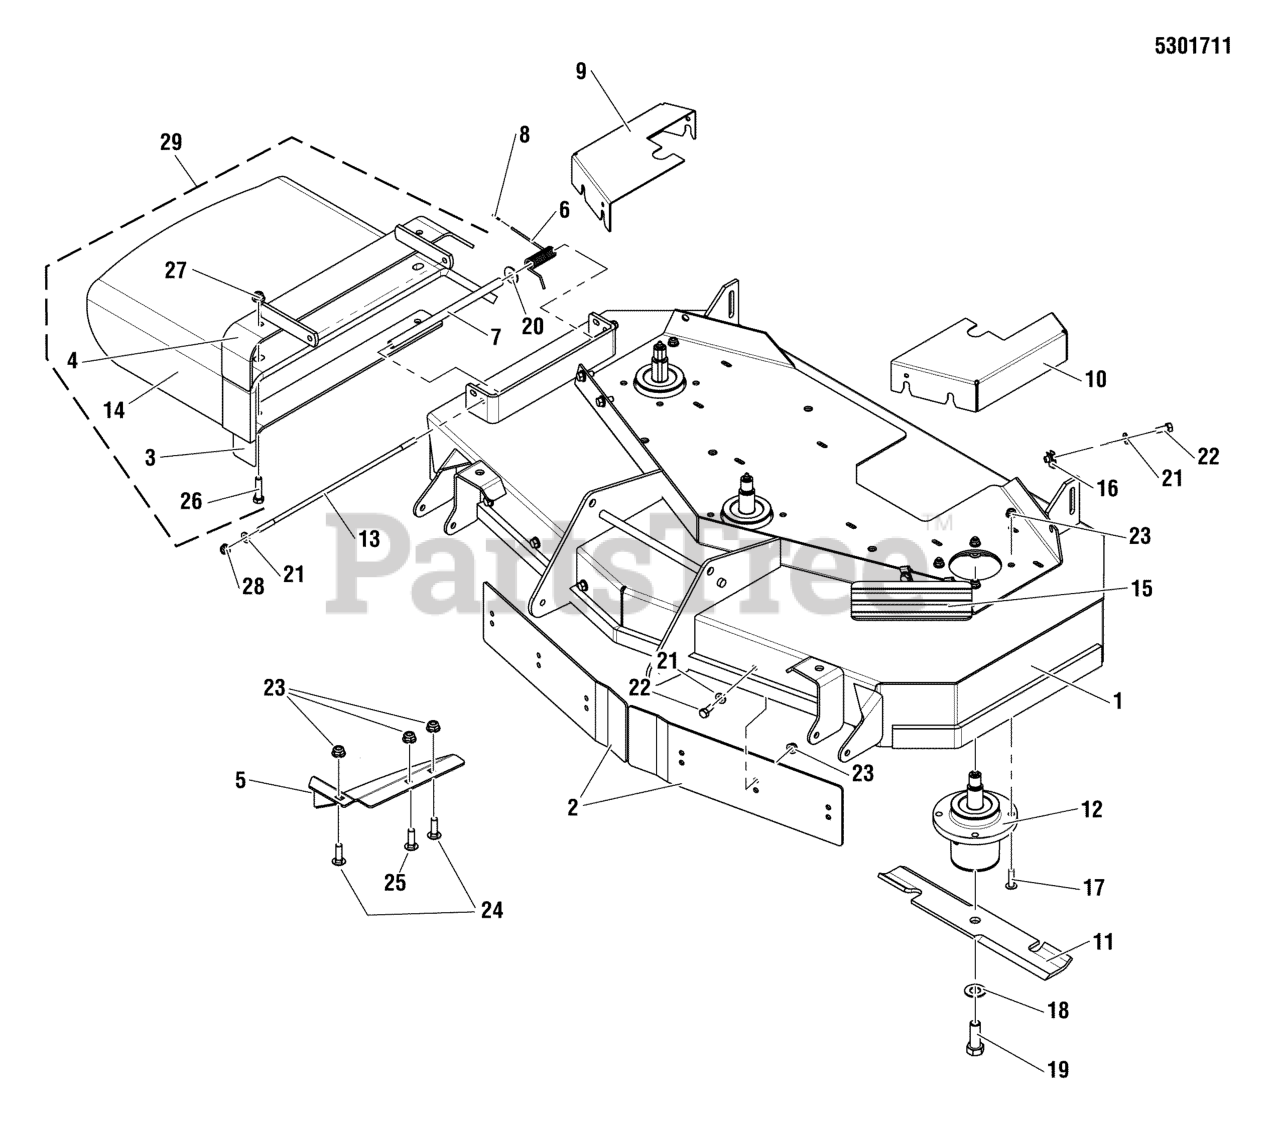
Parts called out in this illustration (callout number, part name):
1	DECK SHELL W/ DECALS, 44SD, IS1500ZCE
2	BAFFLE, FRONT DISCHARGE, 44RD - BLK
3	SUPPORT, DISCHARGE CHUTE, 44/48/52 - BLK
4	WELD, MOUNT, DISCHARGE CHUTE - BLK
5	WELD, DISCHARGE BAFFLE, 44" - BLK
6	SPRING, TORSION
7	SPACER, TORSION SPRING,9.63 LG
8	CAP, PROTECTOR, .120 ID
9	GUARD, 44" MOWER DECK, RH
10	GUARD, 44" MOWER DECK, LH
11	BLADE, 15" (SET OF THREE)
12	ASSM, SPINDLE, LOW PROFILE
13	ROD, 5/16 X 13.75, TBE
14	CHUTE, DISCHARGE, BEND RUBBER, 44/48/52
15	SAFETY WALK, 4.00 X 7.50
16	BODY CLIP, 5/16-18-7GA MATERIAL
17	BOLT, 5/16-18 X 1 1/4 FLANGE
18	WASHER, 5/8 GRADE 8, YZ
19	BOLT, 5/8-11 X 1-3/4 GD8
20	WASHER, 5/16 FENDER
21	WASHER, 5/16" SAE
22	BOLT, 5/16-18 X 3/4 GD5
23	NUT, 5/16-18 HEX NYLOCK FLANGE
24	BOLT, 5/16-18 X 3/4, CARRIAGE
25	BOLT, 5/16-18 X 1, CARRIAGE
26	BOLT, 3/8-16 X 1-1/2" GD5 CZ
27	NUT, 3/8-16 HEX NYLOCK FLANGE
28	NUT, 5/16-24 HEX NYLON LOCK
29	KIT, DISCHARGE CHUTE, 44/48/52
